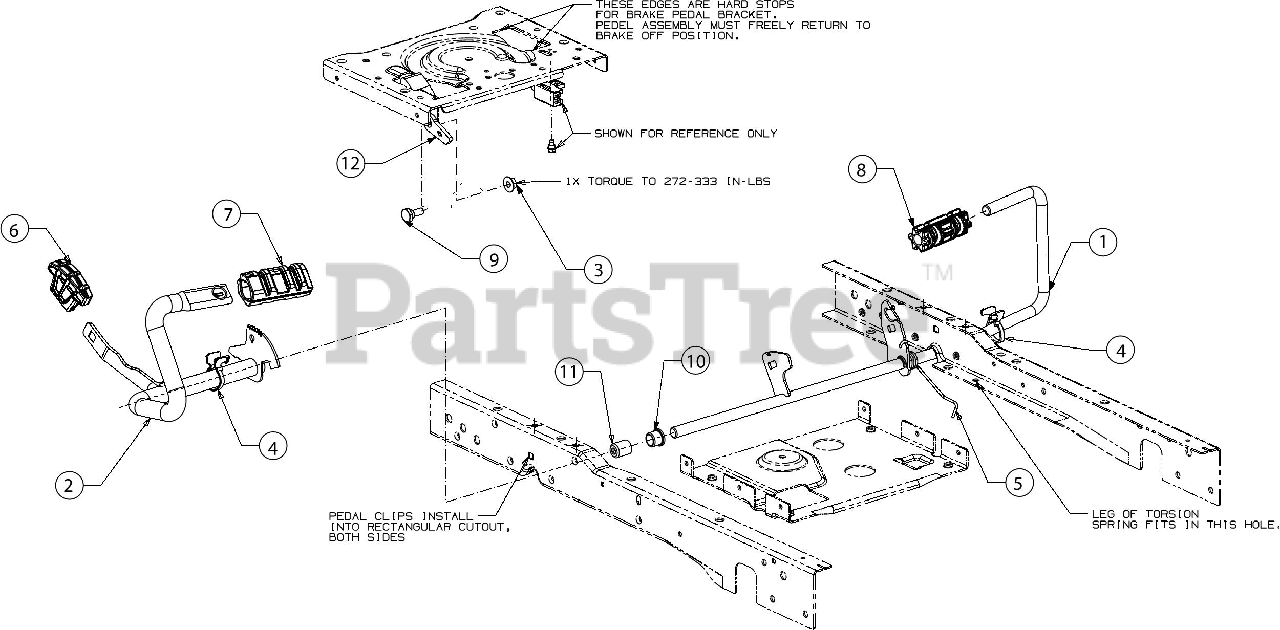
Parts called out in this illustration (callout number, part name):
1	BRAKE PEDAL ASSEMBLY
2	FORWARD/REVERSE PEDAL ASSEMBLY
3	FLANGE LOCK NUT
5	TORSION SPRING
6	REVERSE PEDAL PAD
7	FORWARD PEDAL PAD
8	BRAKE PEDAL PAD
9	SHOULDER SCREW
10	FLANGE BEARING .63X.84X.71
11	PLASTIC SLEEVE BEARING
12	CRUISE LATCH
